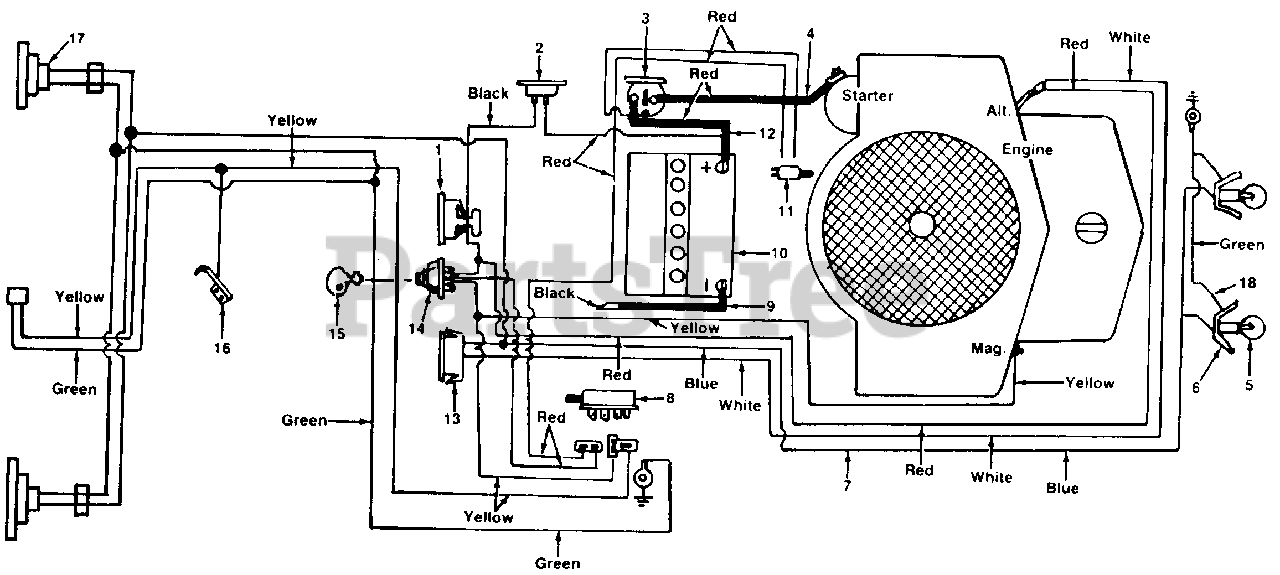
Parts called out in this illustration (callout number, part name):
1	Ammeter
2	Circuit Breaker
3	Solenoid
4	Wire
5	Bulb
6	Socket
7	Wire Harness-w/o Taillights
8	Safety Switch
9	6 Ga. Black Wire
10	Battery 12V
11	Safety Switch
13	Light Switch
14	Ignition Switch
15	Ignition Key
16	Spring Switch
17	Taillight
18	Ground Wire
